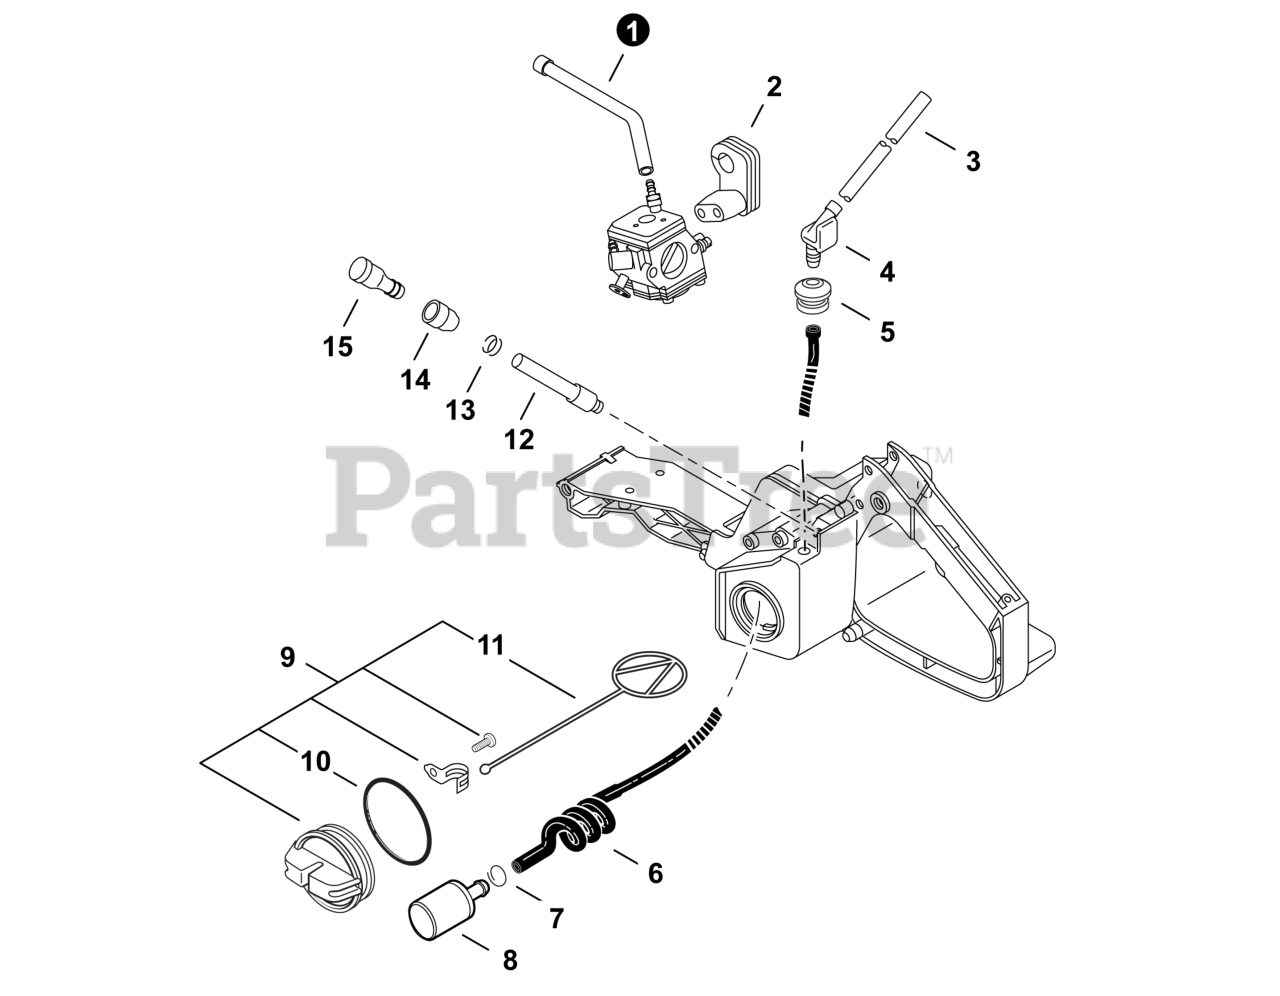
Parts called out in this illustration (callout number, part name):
1	PIPE, IMPULSE
2	GROMMET, NEEDLE
3	PIPE, FUEL 3×6×110
4	CONNECTOR, PIPE
6	PIPE, FUEL
7	CLIP Ø6.5 MM
8	FILTER, FUEL
9	CAP ASSY, FUEL
10	O-RING 29
11	CONNECTOR, CAP L= 60 MM
12	PIPE, VENT
13	CLIP Ø6.5 MM
14	HOLDER, VENT
15	VENT ASSY
